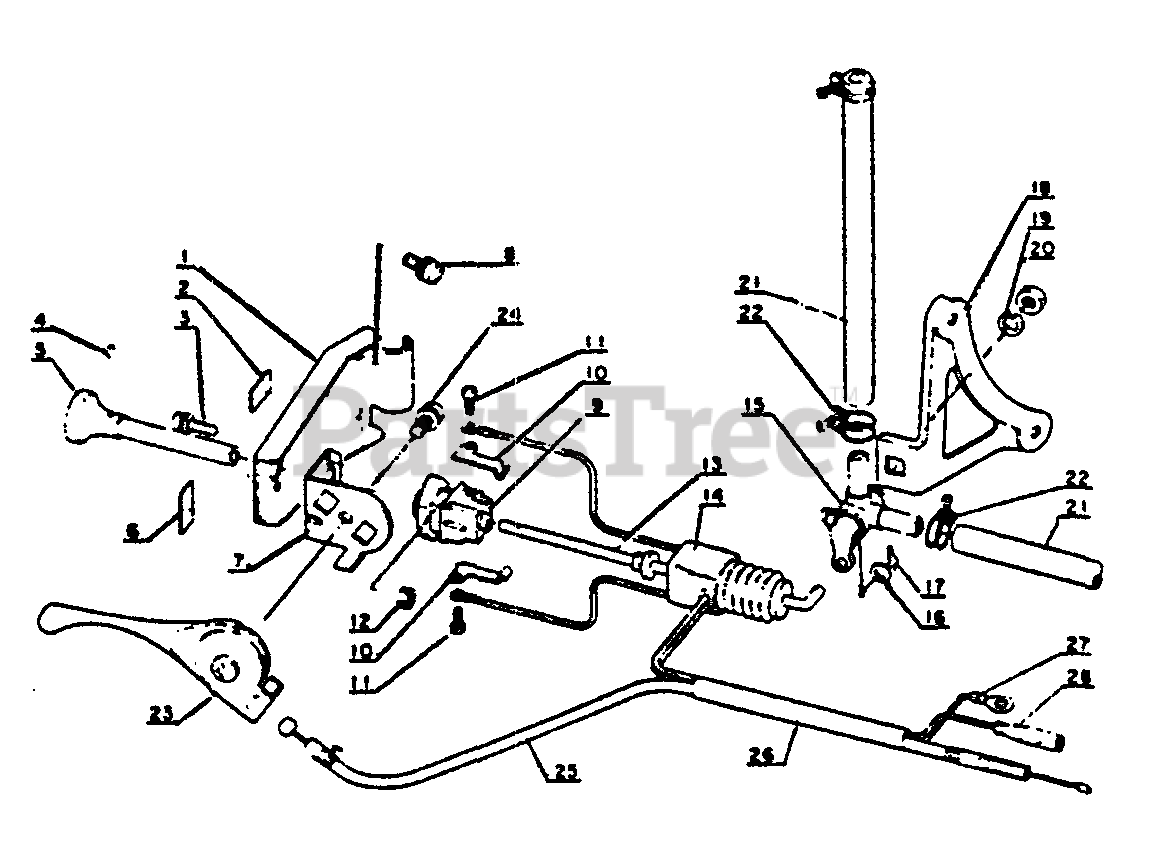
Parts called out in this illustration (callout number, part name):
1	BRACKET, SWITCH
2	LABEL - STOP
3	SCREW 4×12
4	PIN, SPRING 16×10
5	KNOB
6	LABEL - SAFETY
7	BRACKET, THROTTLE LEVER
8	SCREW 5×10
9	BODY, SWITCH
10	PLATE, SWITCH
11	SCREW 3×6
13	ROD
14	BRACKET, SWITCH
15	FUEL VALVE ASSY
16	WASHER 4 MM
18	BRACKET, FUEL VALVE
19	LOCKWASHER - 6
21	PIPE, FUEL
22	CLAMP
23	LEVER, THROTTLE
24	SCREW 5×12
25	THROTTLE CONTROL ASSY
26	CABLE, THROTTLE
27	LEAD - GROUND
28	LEAD
